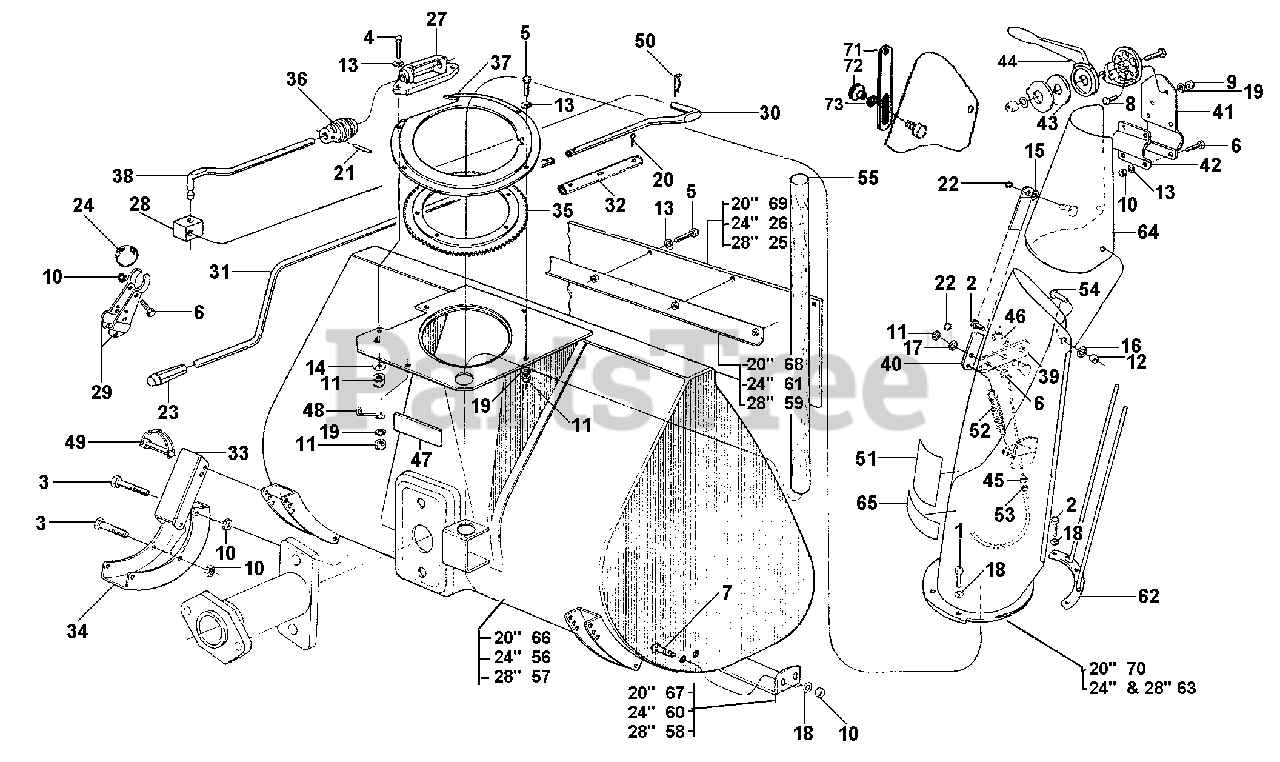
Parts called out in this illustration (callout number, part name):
1	SCREW TE M6X10 UNI 5739-5S
2	SCREW TE M6X14
3	SCREW TE M6X55
4	SCREW M6X25
5	SCREW TE M6X16
6	SCREW M6X20
7	SCREW M6X16
8	SCREW TSV M6X16 UNI 260-5S
10	NUT, SELF LOCKING M6
11	NUT, SELF LOCKING M6
12	NUT, SELF LOCKING M10
13	WASHER, FLAT 6.4
14	WASHER, FLAT
16	WASHER, FLAT 10.5X21
17	WASHER, FLAT 6.4
18	SUPER WASHER 6 DIN 6796
19	WASHER, LOCK 6.4
20	COTTER PIN A 3X20 UNI 1336
21	PIN, LOCKING SW 3X22 SPIRAL
22	RETAINING RING
25	MUD FLAP 70 CM
26	MUD FLAP 60 CM
27	SCREW SUPPORT
29	GUIDE SUPPORT
30	FUNNEL CONTROL ROD SHORT
31	FUNNEL CONTROL ROD LONG
32	CONTROL ROD EXTENSION
38	ROD EXTENSION
40	FLAP TIEROD
41	LEVER SUPPORT
43	RING FOR LEVER
44	SNOW THROWER HANDLE
45	END, SHEATH
46	PIN, CABLE CLAMP
48	GAS SHEATH SUPPORT
51	FUNNEL STICKER
52	FUNNEL SPRING
53	ROCKER ARM WIRE AND SHEATH
54	SCREW M10X25
56	SNOW THROWER CRANKCASE 60 CM
57	SNOW THROWER CRANKCASE 70 CM
58	BLADE 70 CM
59	MUD FLAP STOP 70 CM
60	BLADE 60 CM
61	MUD FLAP STOP 60 CM
62	FUNNEL GRATE
63	SNOW THROWER FUNNEL
65	STICKER " MADE IN ITALY"
66	SNOW THROWER CRANKCASE 50 CM
67	BLADE 50 CM
68	MUD FLAP STOP 50 CM
69	MUD FLAP 50 CM
70	SNOW THROWER FUNNEL
71	CONTROL LEVER - 20
73	WASHER FLAT M10 5X18 - 20
